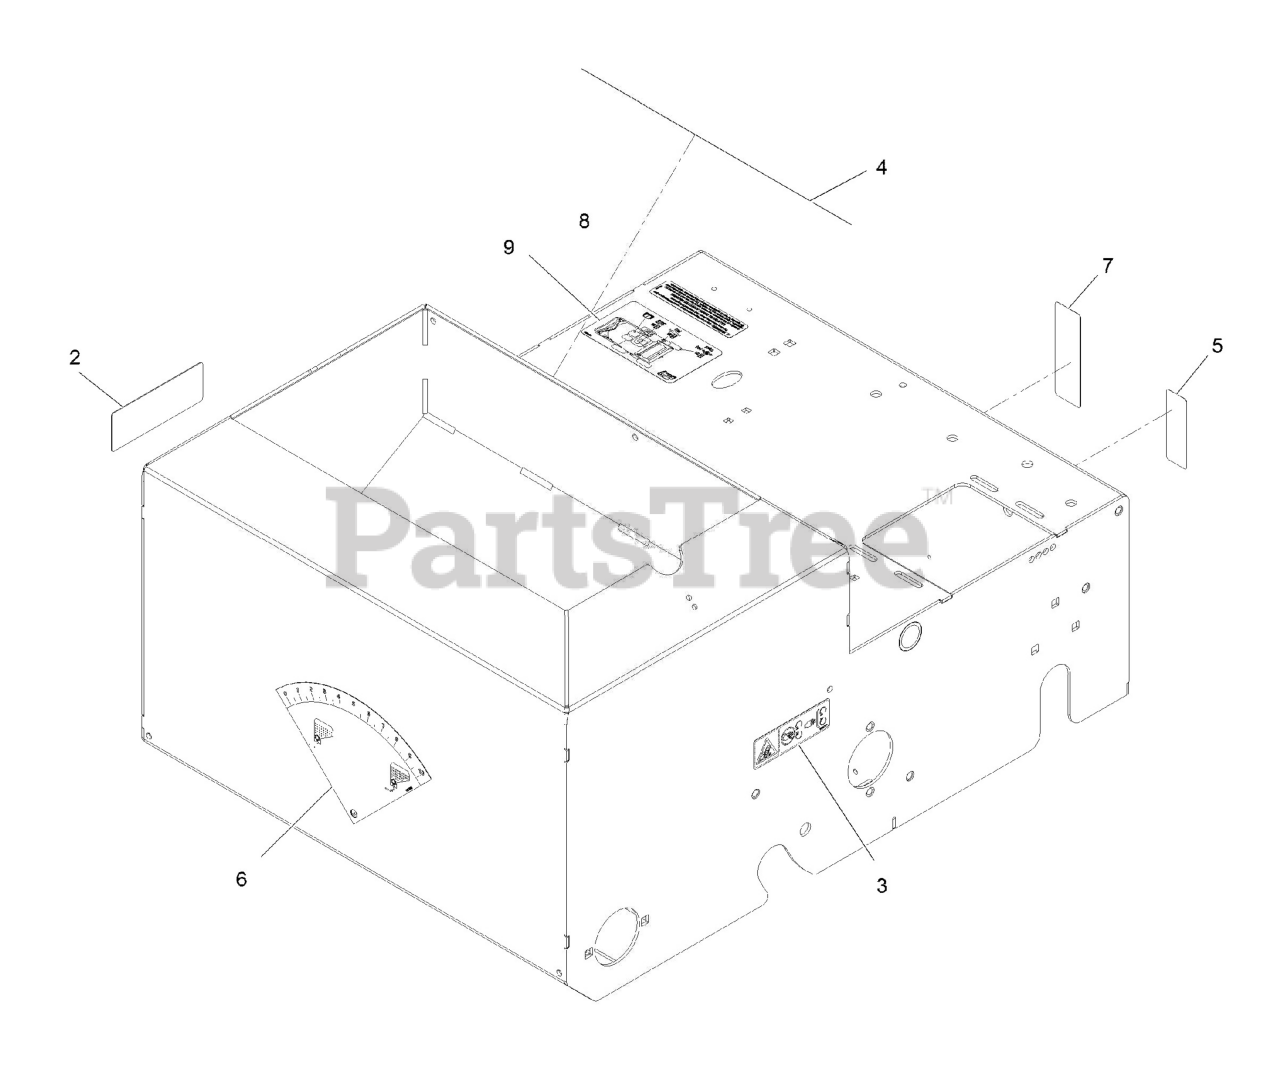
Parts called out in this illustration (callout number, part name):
2	DECAL-DANGER
3	DECAL-WARNING
4	DECAL-WARNING
5	DECAL-BRAKE, PARKING
6	DECAL-FLOW, SEED
7	DECAL-BYPASS
8	DECAL-ARRESTOR, SPARK
9	Decal-Service Aid Seeder
